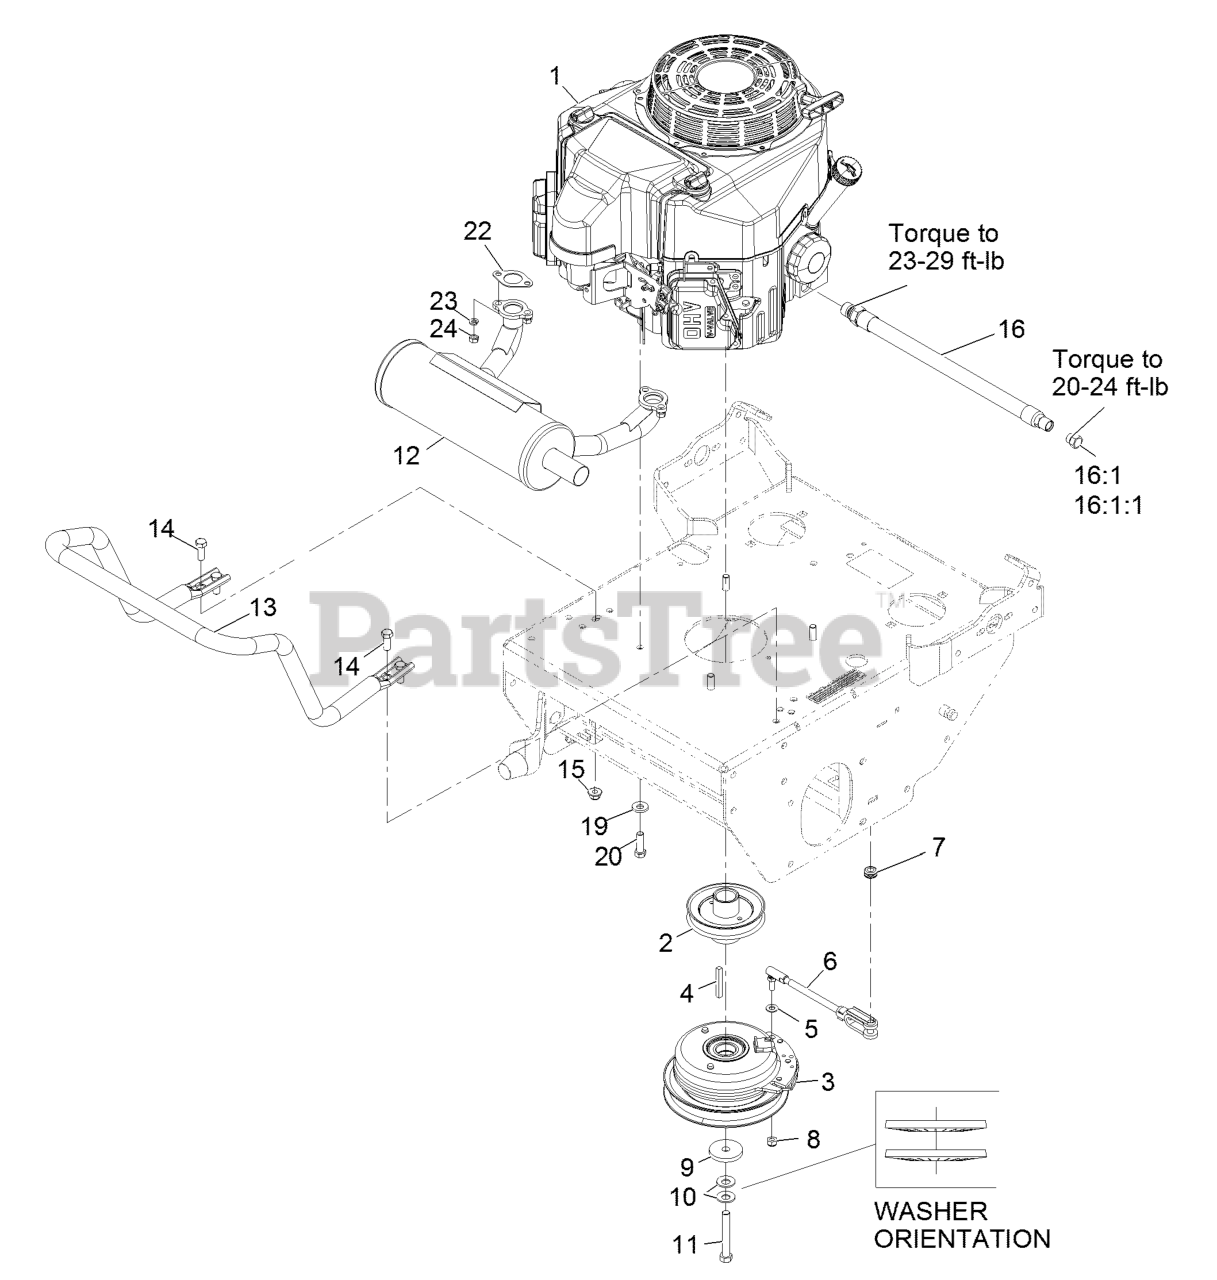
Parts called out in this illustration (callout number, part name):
2	SHEAVE, W/ HUB
3	CLUTCH, 105 FT/LBS, 1.13
4	KEY-SQUARE
5	WASHER-PLAIN
6	ASM, CLUTCH ANCHOR
7	GROMMET
8	NUT-LOCK
9	WASHER-CLUTCH
10	WASHER-SPRING
11	SCREW-HH
12	MUFFLER-HORIZONTAL
13	GUARD-MUFFLER
14	SCREW-HH
15	NUT-HF, NI
16	ASM, ENGINE OIL DRAIN HOS
16:1	PLUG-HH
16:1:1	O-RING
19	WASHER-BELLEVILLE
20	SCREW-HH
22	GASKET-EXHAUST
23	WASHER-LOCK
